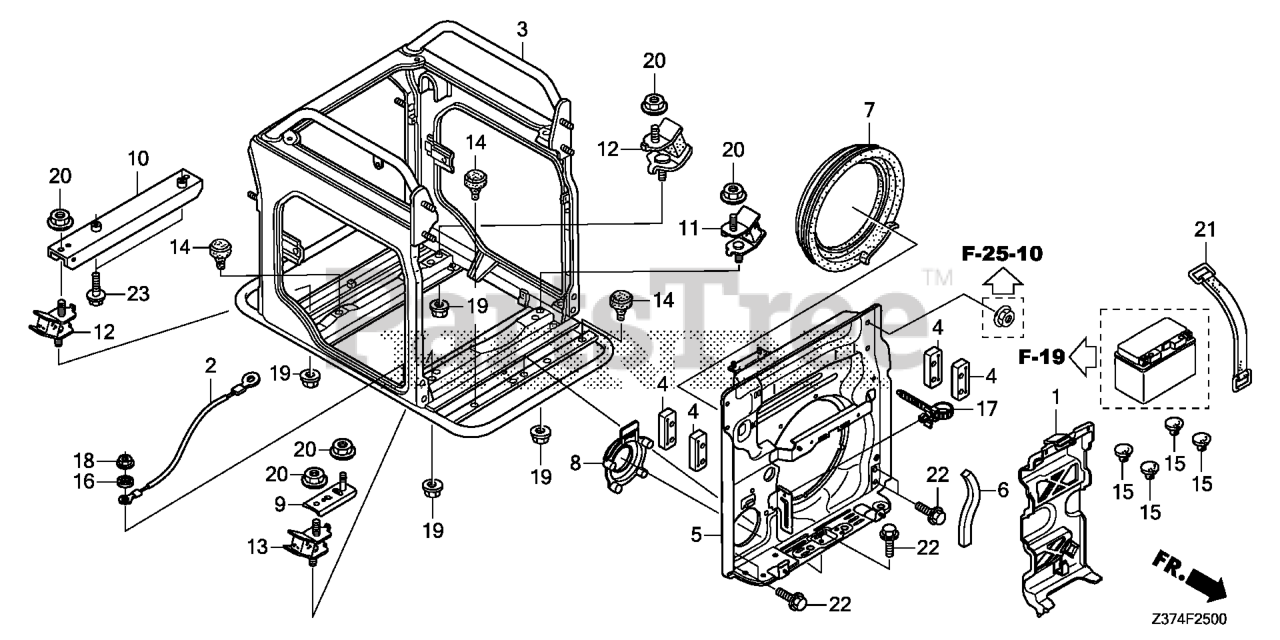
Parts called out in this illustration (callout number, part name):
1	BRACKET, WIRE HARNESS CLIP
2	CABLE, SUB-GROUND
3	FRAME *NH105* (COO) (MAT BLACK)
4	SEAL D, FR. COVER
5	FRAME, FR.
6	SEAL (30X30X250)
7	RUBBER A, SEPARATOR SEAL
8	RUBBER B, SEPARATOR SEAL
9	BRACKET, FR. ENGINE MOUNT *NH105* (MAT BLACK)
10	BRACKET, RR. ENGINE MOUNTING
11	RUBBER (LOWER)
12	RUBBER (LOWER)
13	RUBBER, L. (LOWER)
14	RUBBER, STOPPER
15	RUBBER, BATTERY BOX
16	WASHER, LOCK (6MM)
17	STRAP, CABLE (105MM) *NH1* (Honda Code 1685536). (BLACK)
18	NUT, FLANGE (6MM)
19	NUT, FLANGE (8MM)
20	NUT, FLANGE (10MM)
21	BAND F, BATTERY (155MM)
22	BOLT, FLANGE (8X12)
23	BOLT, FLANGE (8X30)
